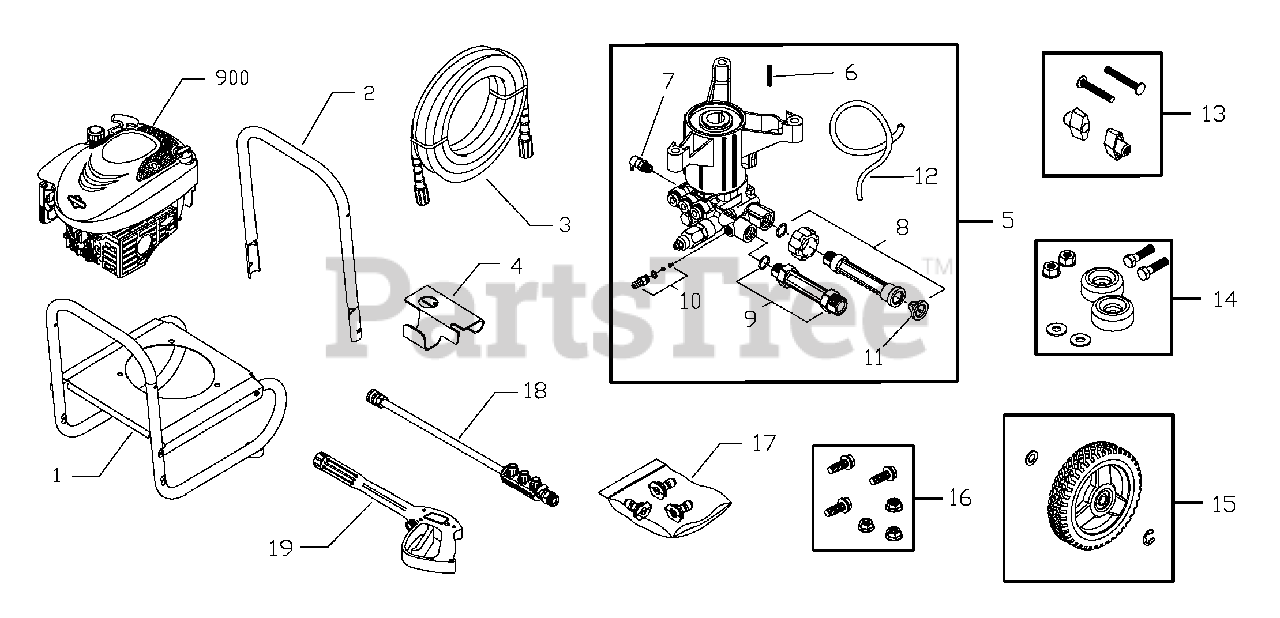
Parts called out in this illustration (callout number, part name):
3	HOSE
5	PUMP
7	VALVE, Thermal Relief
8	KIT, Water Inlet
10	KIT, Chemical Injection
11	FILTER, Garden Hose
12	HOSE, Chemical
13	KIT, Hardware, Handle
14	KIT, Vibration Mount
16	KIT, Hardware, Pump Mounting
17	KIT, QC Nozzles
19	GUN
900	* ENGINE
